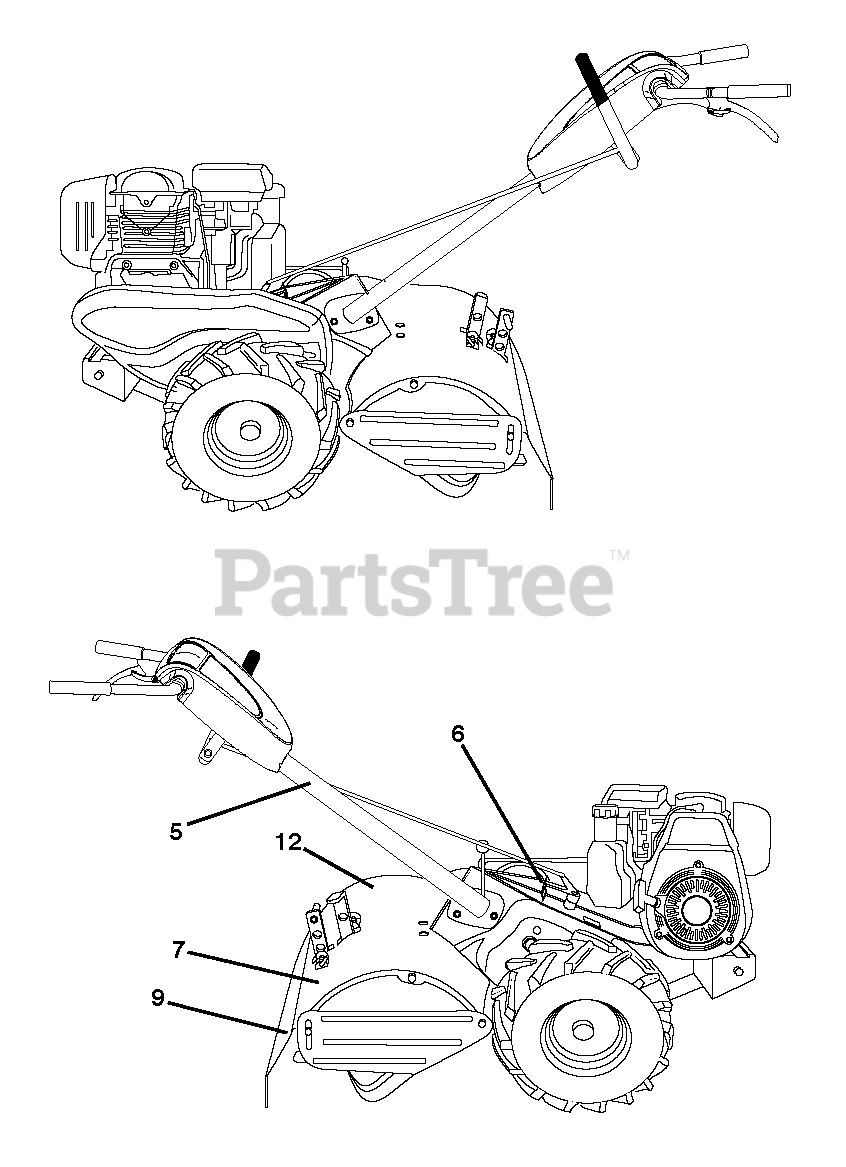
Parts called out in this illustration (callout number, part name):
5	DECAL TI (2 2)
6	DECAL.SHIFT.INDICATOR.DRT
7	DECAL.REVERSE.HUSQ.TILLER
9	DECAL.DRT.WARN.ENG/F
12	DECAL.FOWARD.HUSQ.TILLER
